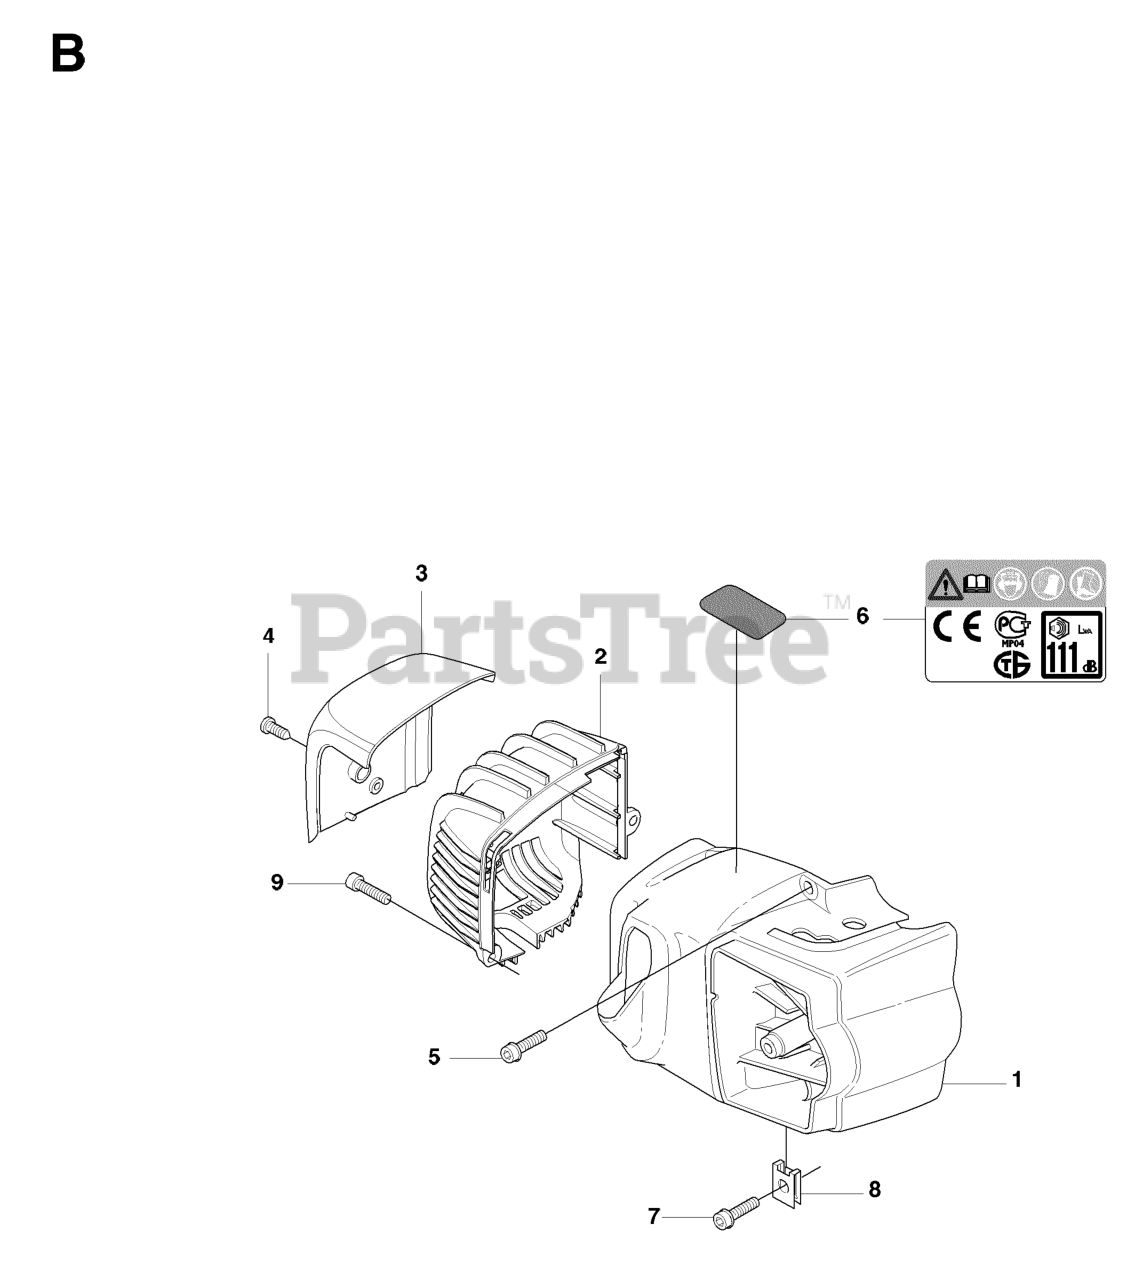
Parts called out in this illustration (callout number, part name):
1	CYLINDER COVER CAPTIVE SCREWS
2	HEAT PROTECTOR
3	MUFFLER SHIELD
6	LABEL WARNING CE
9	SCREW W/ LOCKING FLUID
